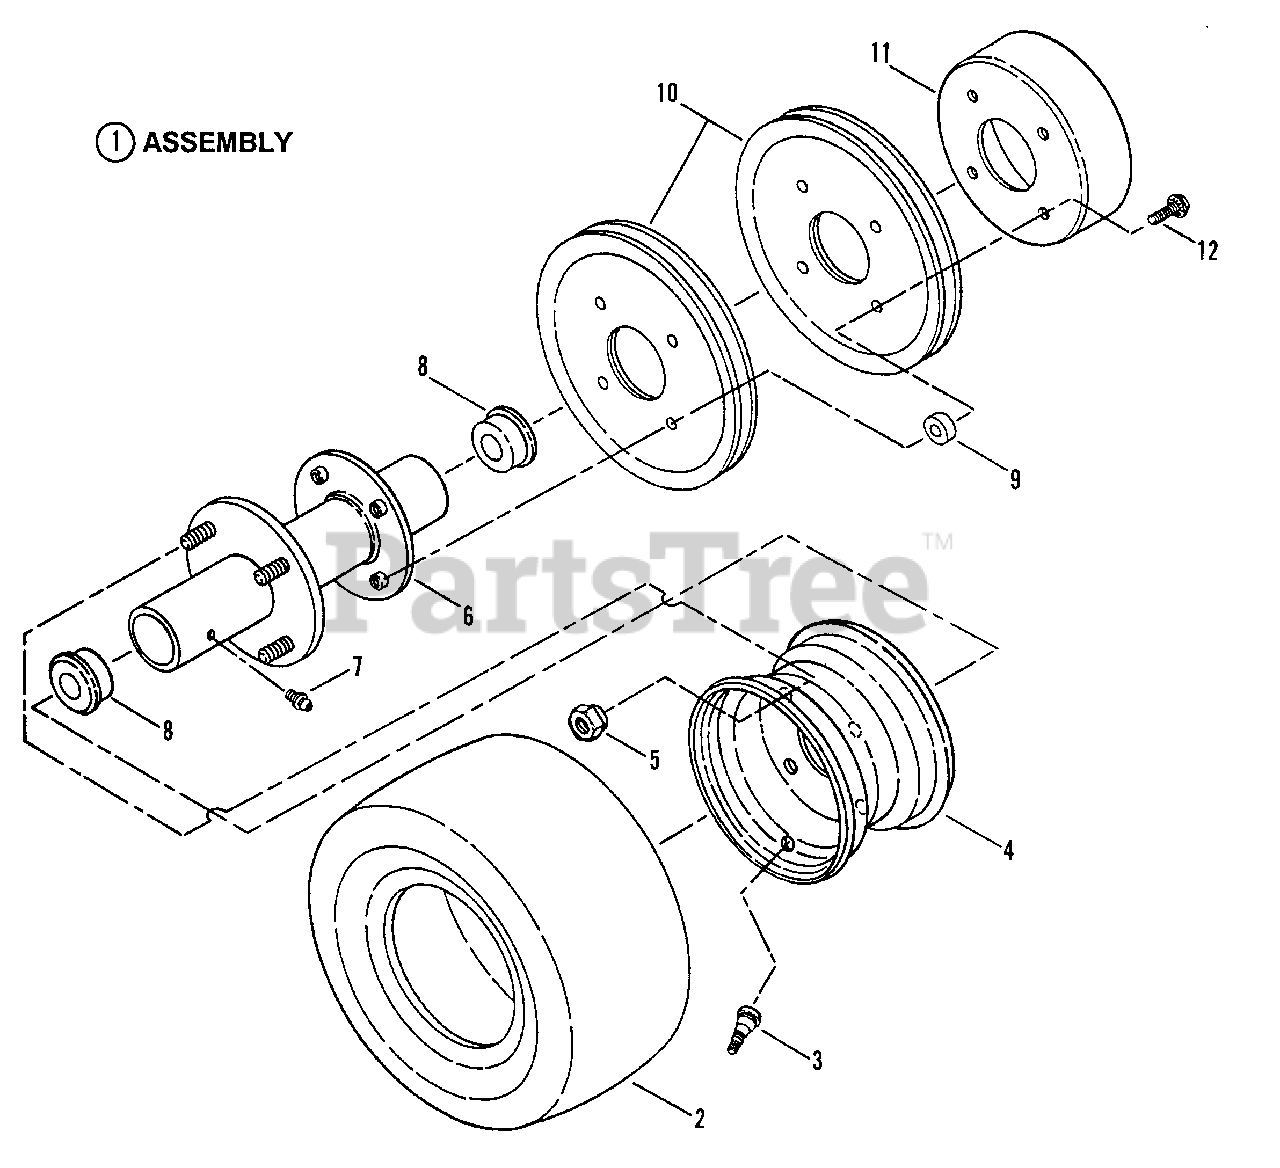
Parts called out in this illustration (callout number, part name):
1	ASSEMBLY, Rear Tire & Rim
2	TIRE, 16/6.50 x 8 Tubeless
3	VALVE, Air (Snap-In)
4	RIM
5	LUG-NUT, 1/2-20 Tapered
6	HUB, Weldment
7	FITTING, Lube
8	BEARING, Wheel
9	SPACER
10	PULLEY, 8"
11	DRUM, Brake, 6"
12	BOLT, 5/16-18 x 1 1/2" Hex Flange Lock, Grade 5
